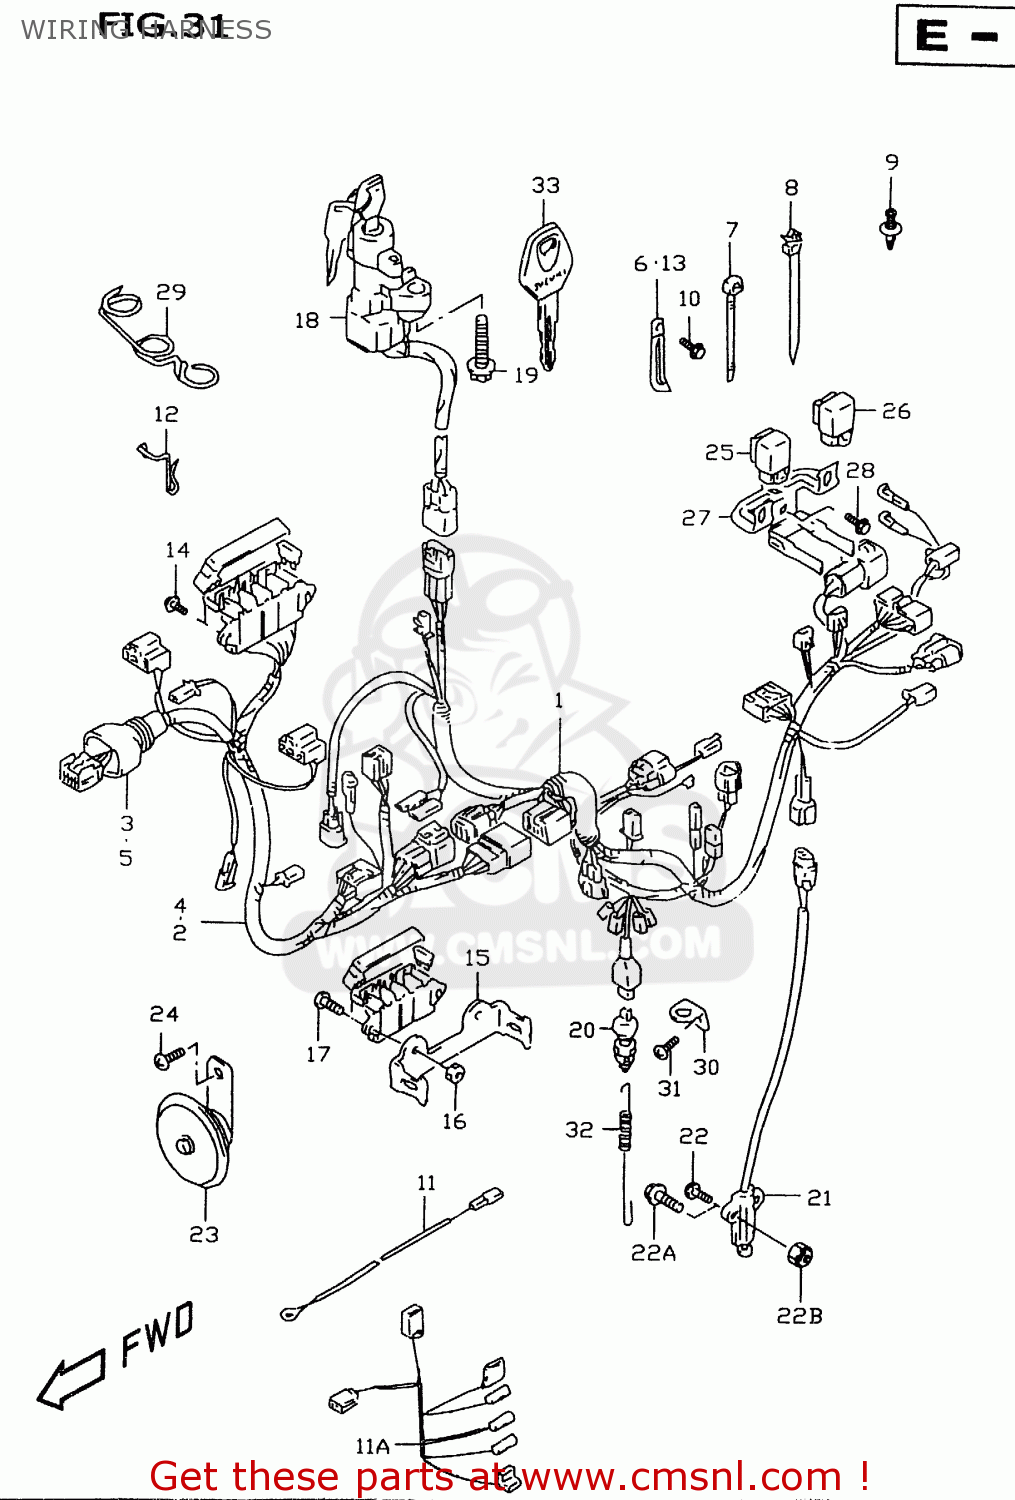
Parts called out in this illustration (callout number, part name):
1	HARNESS,WIRING NO.1
2	HARNESS,WIRING NO.2
3	COVER,SPEEDOMETER COUPLER
4	HARNESS, WIRING NO. 2
5	COVER,SPEEDOMETER COUPLER
6	CLAMP(L:45)
7	CLAMP(L:125)
8	CLAMP
9	CLIP(BLACK)
10	BOLT
11	WIRE,OIL PRESSURE SWITCH LEAD
11A	WIRE,CARB HEATER
12	STOPPER,FUSE BOX
13	CLAMP(L:80)
14	SCREW
15	BRACKET,FUSE BOX
16	NUT,COWLING SCREEN
17	SCREW 5X12
18	LOCK ASSY,STEERING
19	BOLT(8X20)
20	SWITCH ASSY,STOP LAMP
21	SWITCH ASSY,SIDE STAND WARNING
22	BOLT 6X20
22A	BOLT
22B	NUT
23	HORN ASSY
24	SCREW(8X14)
25	RELAY ASSY
26	RELAY ASSY
27	BRACKET,SIDE STAND RELAY
28	BOLT
29	GUIDE,WIRING HARNESS
30	BRACKET,STOP LAMP SWITCH
31	SCREW
32	SPRING
33	KEY,BLANK
